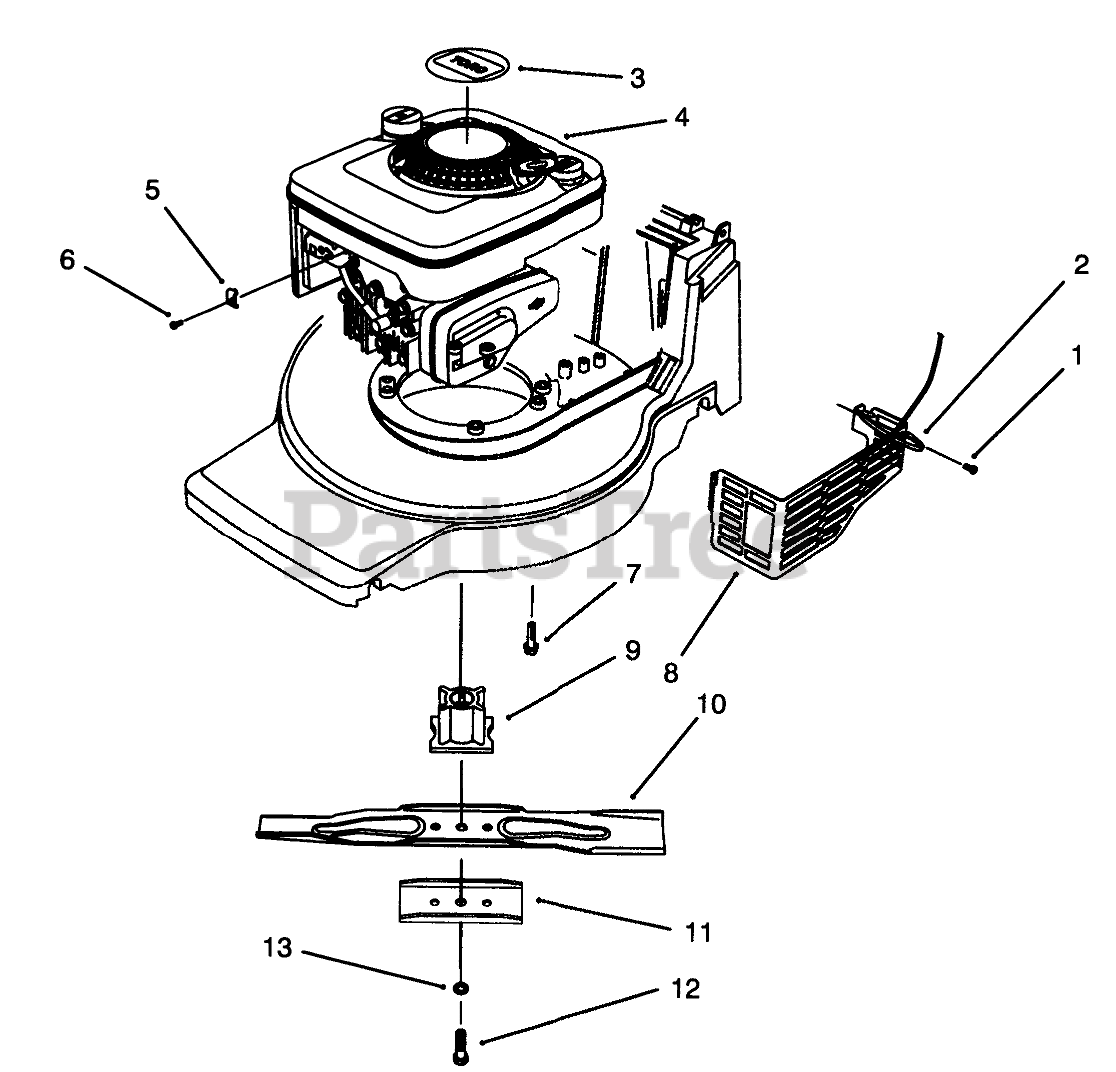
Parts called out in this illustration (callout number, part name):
1	SCREW-HWH
2	TIE-CABLE
3	DECAL - RECOIL
4	Engine-B & S Quantum
5	CLAMP-CASING
6	CLAMP SCREW F/W ENGINE
7	SCREW-HWH
8	SHIELD - MUFFLER
9	BLADE RETAINER - 25 MM
10	Blade
11	Stiffener Blade
12	BOLT-BLADE
13	WASHER-LOCK
